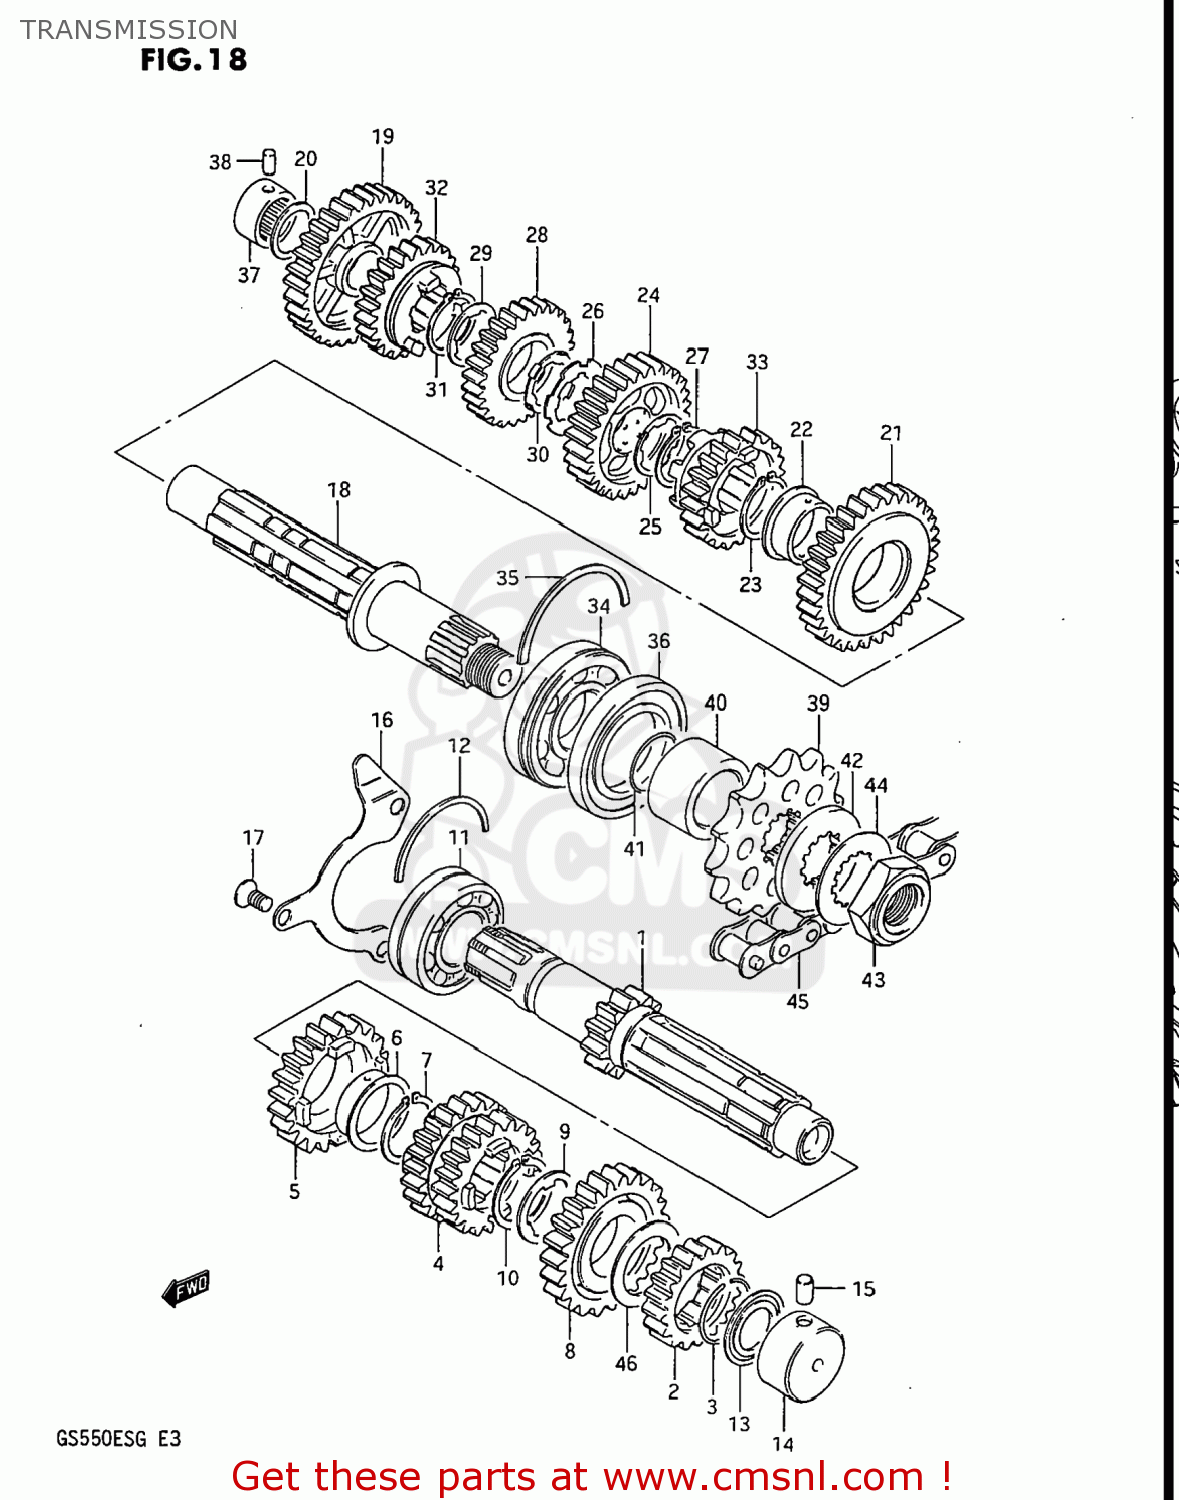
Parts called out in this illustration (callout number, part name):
1	SHAFT,COUNTER
2	GEAR,SECOND DRIVE
3	RING,SNAP
4	GEAR,THIRD/FOURTH DRIVE
5	GEAR,FIFTH DRIVE
6	BUSHING
7	RING,SNAP
8	GEAR,SIXTH DRIVE
9	WASHER,LOCK
10	RING,SNAP
11	BEARING(25X52X19.6)
12	C RING
13	SEAL,OIL(20X31.2X2.7)
14	BEARING(20X34X17.5)
15	PIN
16	PLATE,COUNTERSHAFT BEARING
17	SCREW
18	SHAFT,DRIVE
19	GEAR,FIRST DRIVEN
20	WASHER
21	GEAR,SECOND DRIVEN
22	BUSHING
23	RING,SNAP
24	GEAR,3RD DRIVEN
25	WASHER,LOCK
26	WASHER,LOCK
27	RING,SNAP
28	GEAR,FOURTH DRIVEN
29	WASHER,LOCK
30	WASHER
31	RING,SNAP
32	GEAR,FIFTH DRIVEN
33	GEAR,SIXTH DRIVEN
34	BALL BEARING 25X62X17
35	C-RING
36	SEAL,OIL(33X62X7)
37	BEARING(20X34X20)
38	PIN
39	SPROCKET,ENGINE
40	SPACER (25X33X20.1)
41	O RING(D:1,ID:24.5)
42	SPACER
43	NUT
44	WASHER
45	CHAIN ASSEMBLY,DRIVE
46	SHIM
